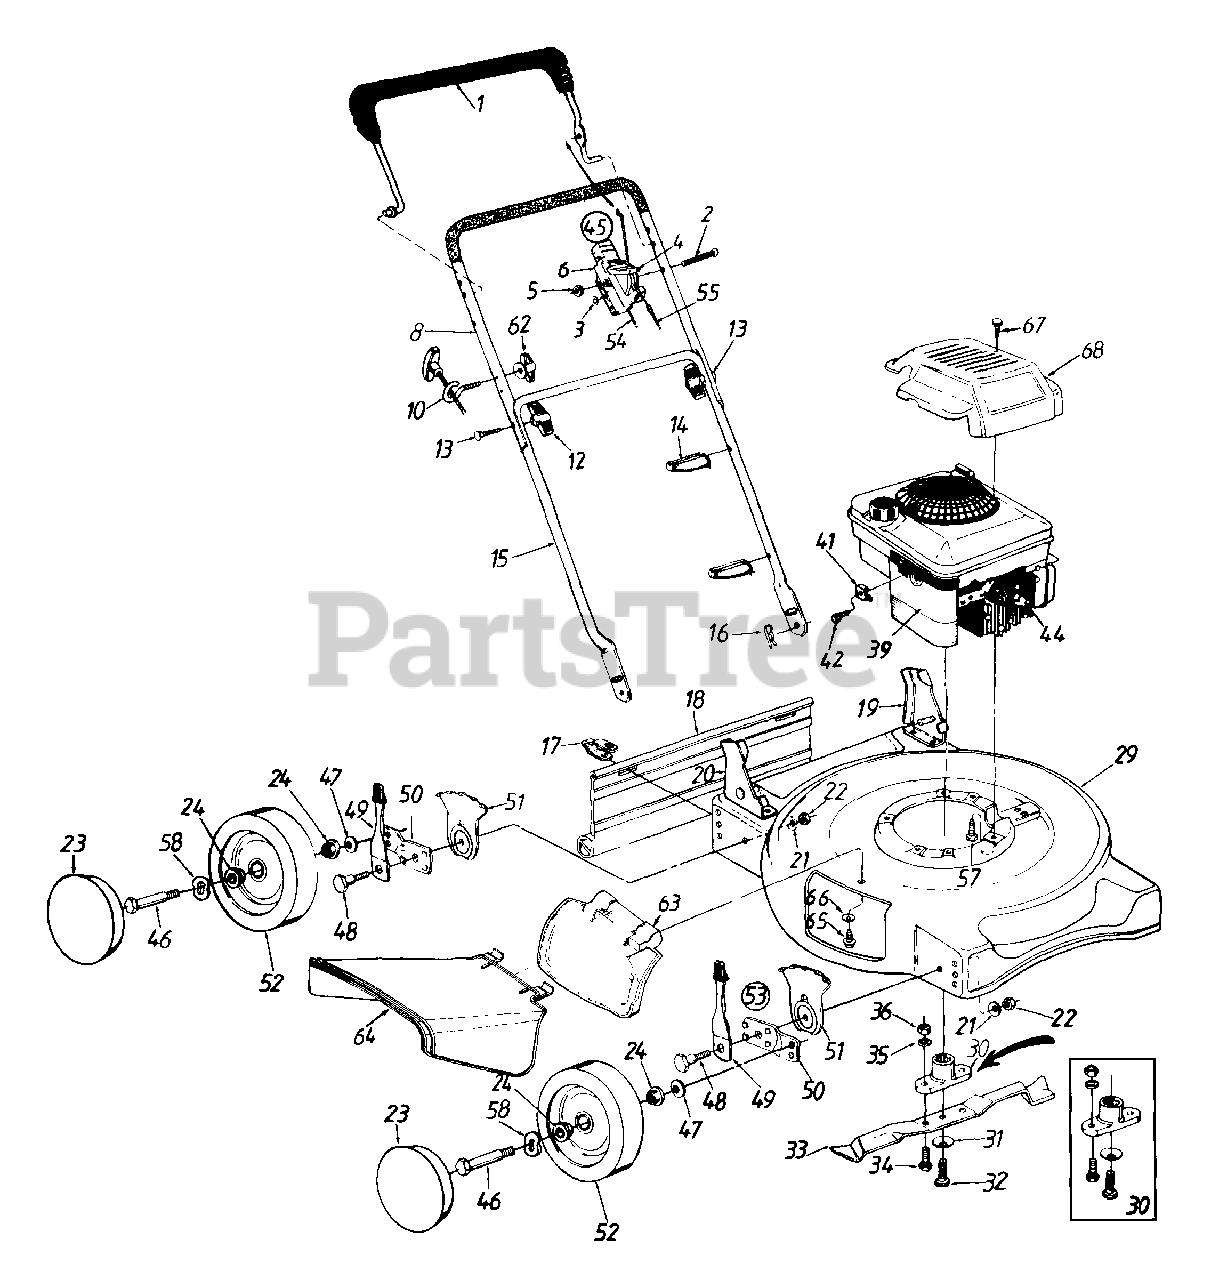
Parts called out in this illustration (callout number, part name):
1	Control Handle Ass'y.
2	Oval C-Sunk Scr.
3	Spr. Wash. .66" I.D.
4	Throttle Lever
5	Hex L-Nut 1/4-20 Thd.
6	Throttle Body
12	Hand Knob
13	Curved Hd. Bolt 5/16-18 x 2" Lg.
14	Cable Tie
16	Hairpin Cotter
17	Hinge Clip
18	Rear Flap
19	Handle Bracket Ass'y. - L.H.
21	Bell-Wash. .39" I.D. x 1.38"
22	Hex Nut 3/8-16 Thd.
23	Hub Cap
24	Bearing
29	20" Deck Ass'y.
30	Blade Adapter Kit
31	Bell-Wash. .39" I.D.
32	Hex Bolt 3/8-24 x 1.5" Lg.
33	20" Mulching Blade
34	Hex Bolt 3/8-24 x 1" Lg.
35	L-Wash. 3/8" I.D.
36	Hex Nut 3/8-24 Thd.
39	Engine
41	Cable Clamp
42	Hex Self-Tap Scr. #10-32 x .62"
44	Spark Plug Boot
45	Throttle Box Comp.
46	Axle Bolt
47	Bell-Wash. .400" I.D. x .88"
48	Shld. Bolt .50" Dia. x .357"
49	Spring Lever Ass'y. w/Knob
51	Height Adj. Plate
52	Wheel Ass'y. Comp.
53	Height Adj. Ass'y. Comp. - R.F. & L.R.
54	Throttle Cable - 51"
55	Control Cable - 36"
58	Wave Washer .51" I.D.
62	Handle Knob 1/4-20 Thd.
63	Mulching Plug
64	Chute Deflector
65	Bell-Wash. 1/4" I.D
66	Hex Wash. Hd. TT-Tap Scr. 1/4-20 x .5" Lg.
67	Hi-Lo Scr. #10 x 1.25" Lg.
68	Engine Shroud
